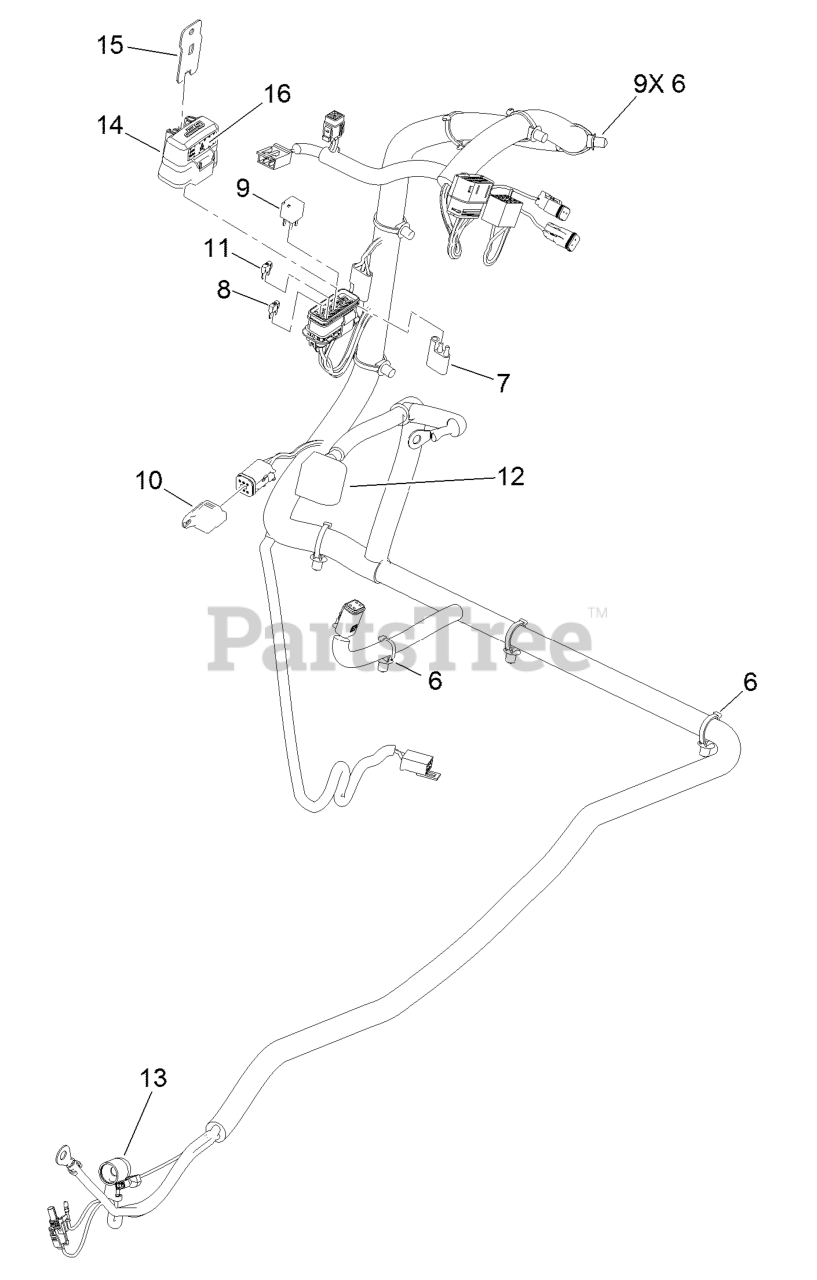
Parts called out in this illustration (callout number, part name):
6	Clip-Tie
7	Cap-Plug
8	Fuse-Mini Blade, 20 Amp
9	Relay-Micro
10	Cap-Plug, 6 Way
11	Fuse-Mini Blade, 15 Amp
12	Insulator-Battery
13	Insulator-Solenoid
14	Cover-Block, Fuse
15	Clip-Mounting
16	Decal-Fuse
